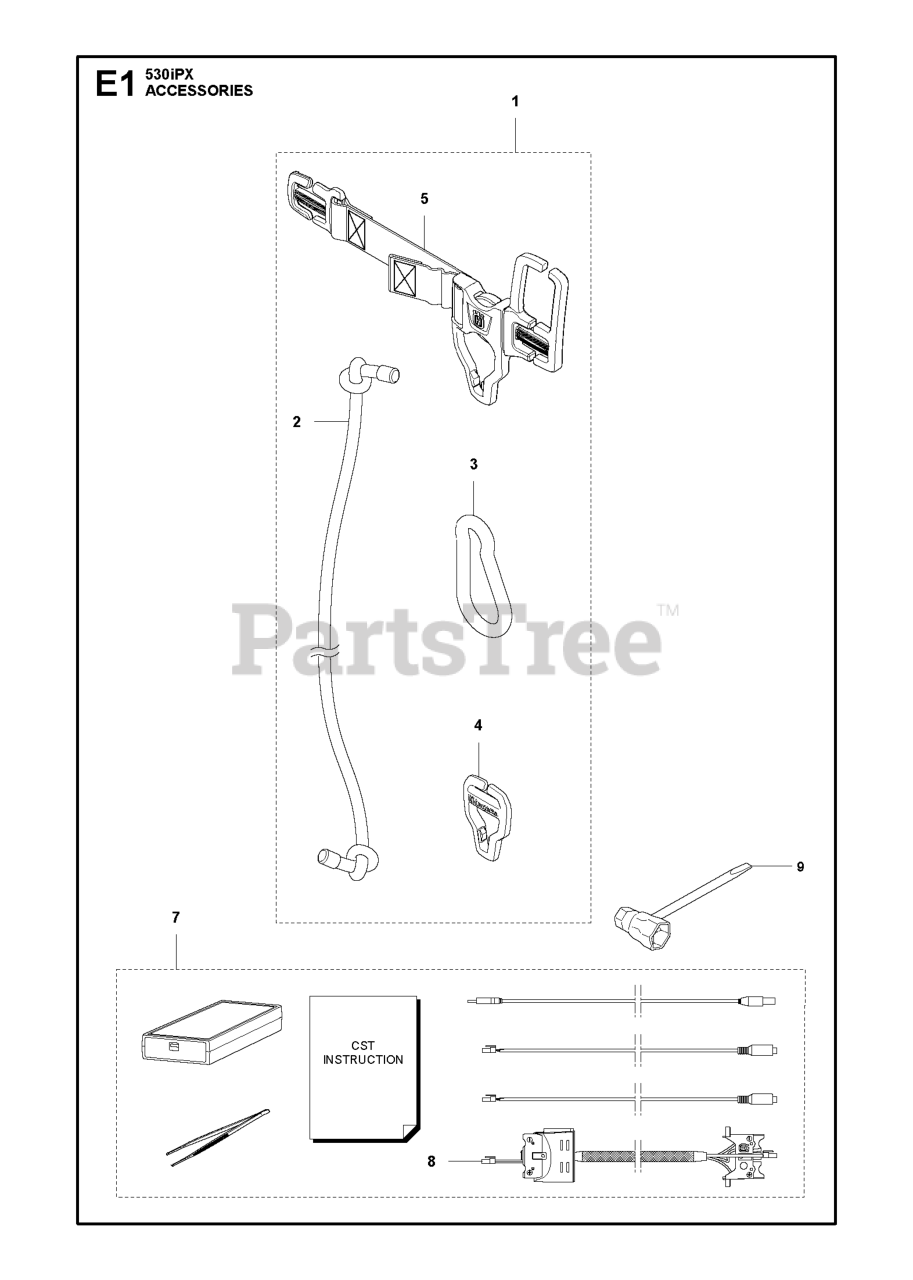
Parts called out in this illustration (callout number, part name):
1	NOSE CONE BH LEFT
2	NOSE CONE BH RIGHT
4	SCREW M4 X 1.75 PT 16MM
7	CLAMP HARNESS LOWER
9	ASSY THROTTLE HOUSING
13	CLAMP HARNESS UPPER
14	KIT D'SHAFT
16	CLAMP BRACKET
18	KIT SWITCH
19	LOCKOUT STARTER THROTTLE
22	THROTTLE LOCK
24	THROTTLE CABLE
26	THROTTLE TRIGGER
28	SCREW
30	FLEXSHAFT 57"
31	HARNESS DUO
32	KIT COBI SHIELD
33	Limiter - Line
36	SUPPORTING CUP
37	SUPPORT FLANGE
38	GEARHEAD NUT - BRUSHCUTTER
39	SCREW - CARB. ADAPTOR
41	DRIVE DISC
42	SCREW 1/4-20 X 7/8 (TAP
43	BRACKET SHIELD STRAIGHT SHAFT
44	ASSY GEARBOX
